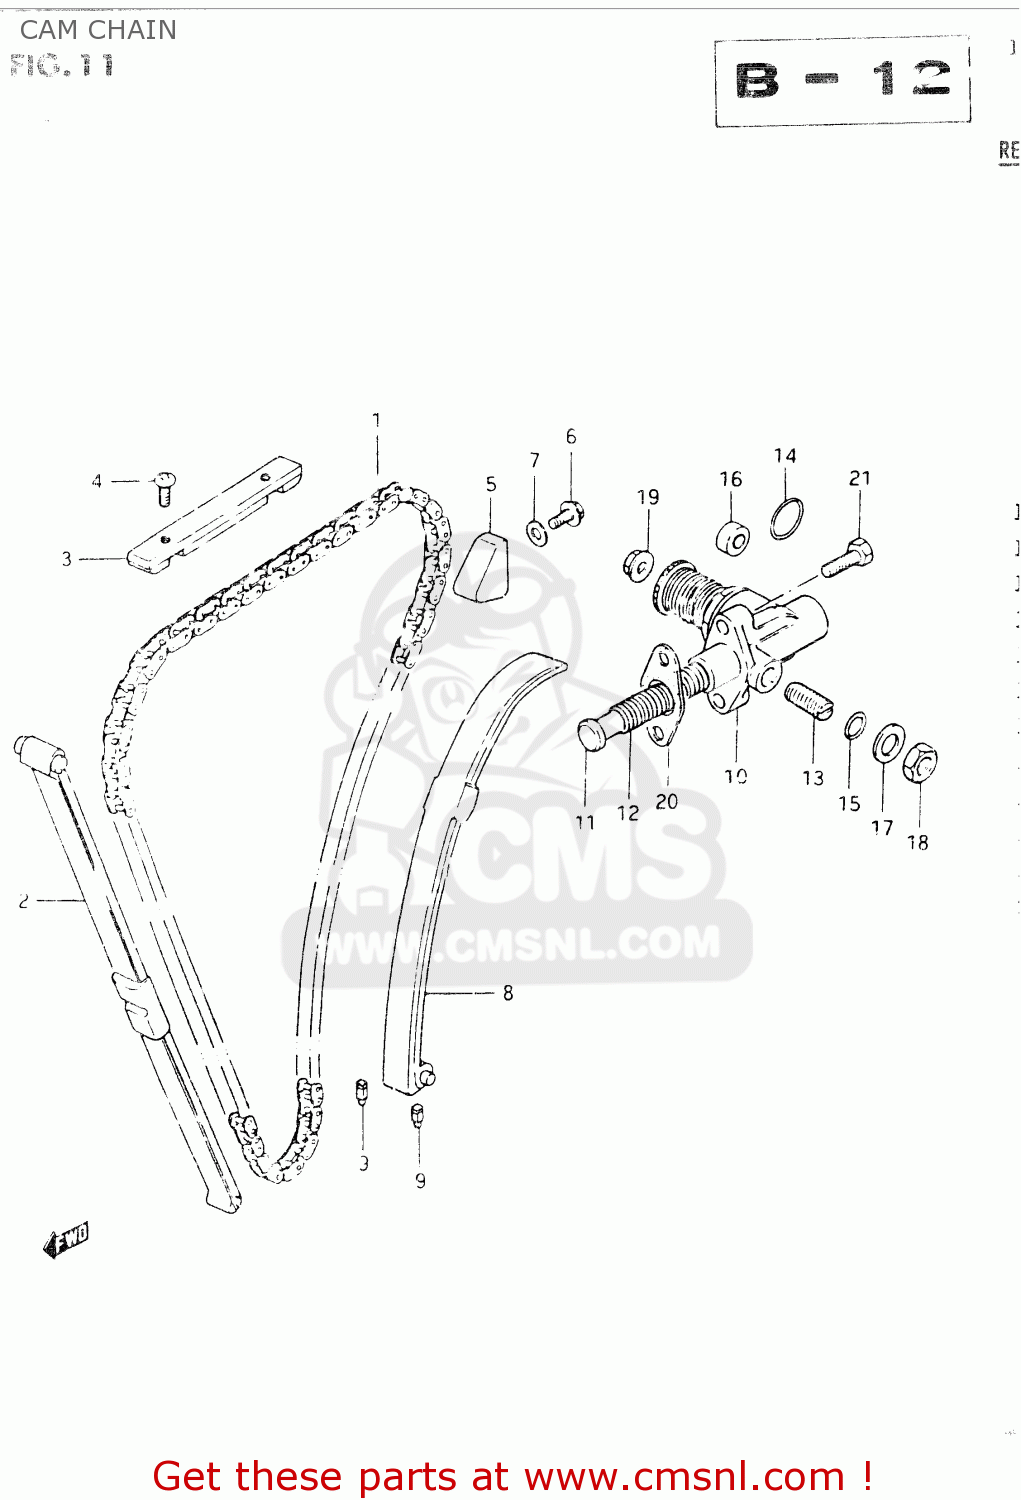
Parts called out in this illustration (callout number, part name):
1	CHAIN,CAMSHAFT DRIVE(120L)
2	GUIDE, CAM CHAIN NO.1
3	GUIDE,CAM CHAIN NO.3
4	SCREW
5	GUIDE,CAM CHAIN
6	BOLT 6X12
7	WASHER
8	TENSIONER,CAM CHAIN
9	CUSHION,CAM CHAIN TENSIONER
10	ADJUSTER ASSEMBLY,TENSIONER
11	ROD,PUSH
12	SPRING
13	SCREW,TENSIONER ADJUST
14	O RING(D:2.4,ID:20.8)
15	O RING(D:1.9,ID:5.7)
16	SEAL,OIL(10X16X4)
17	WASHER
18	NUT
19	NUT 6MM
20	GASKET,TENSIONER ADJUSTER (MCA)
21	SCREW
